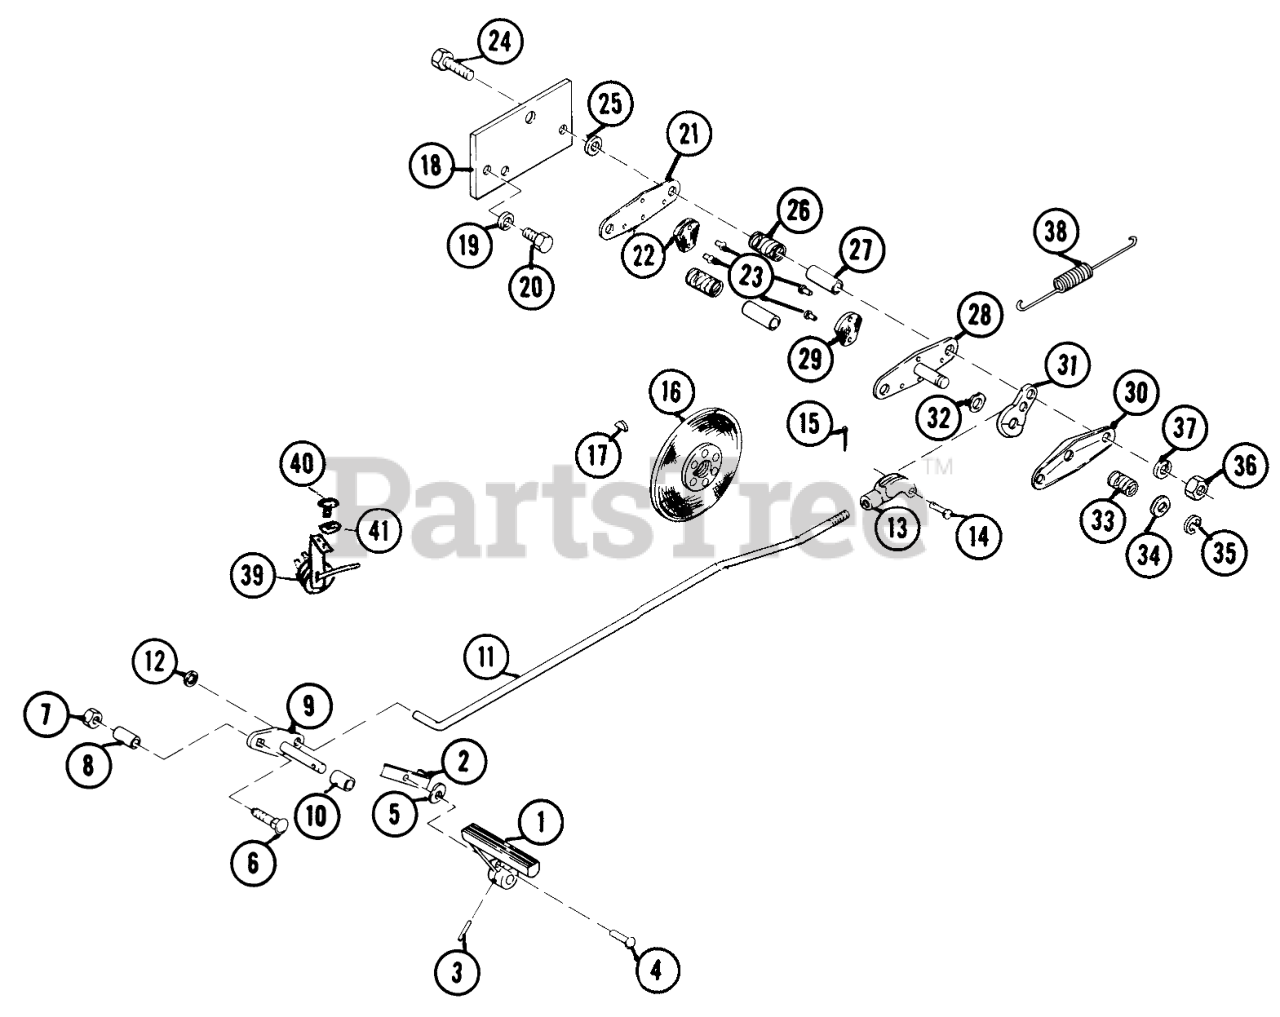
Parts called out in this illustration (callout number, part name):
4	Rivet
21	Inner Brake Pad (with Lining)
22	Lining, Inner Pad
23	Rivet
25	Washer, 1/4 Plain
27	Bushing, Split (Pad to Pad)
28	Outer Brake Pad
29	Lining, Inner Pad
30	V Plate
31	Cam Lever
32	Washer, 5/16 x .31
33	Spring ("V" Plate to Pad)
34	Washer
35	Retaining Washer
